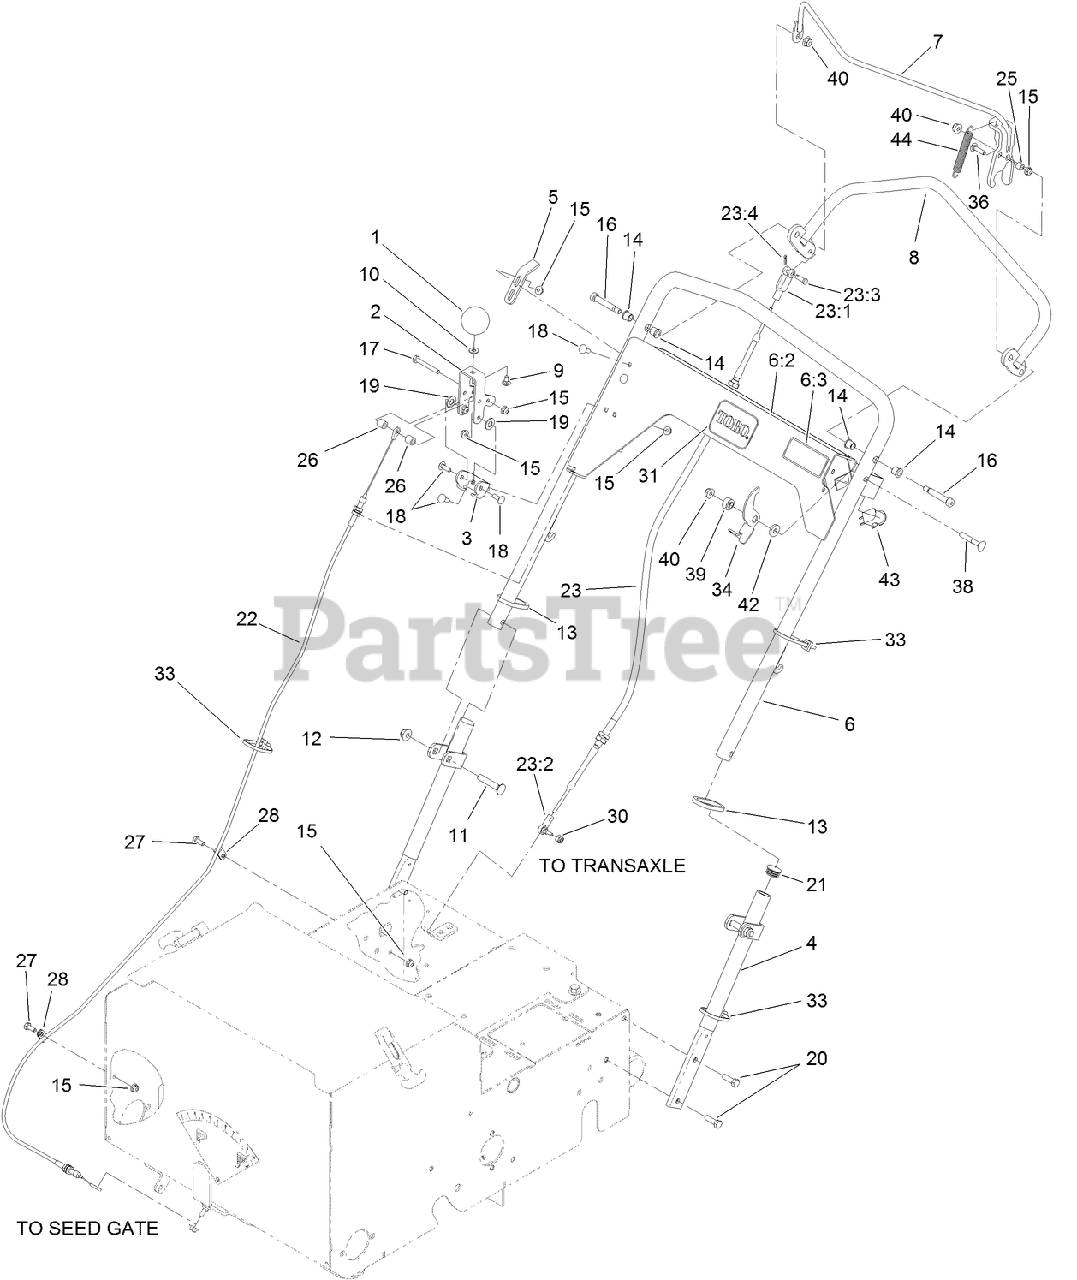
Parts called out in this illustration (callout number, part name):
1	KNOB-RATE, FLOW
2	LEVER-ADJUST, FLOW
3	BRACKET-ADJUST, FLOW
4	HANDLE-LOWER
5	BRACKET-ADJUST, DRIVE
6	HANDLE
6:2	DECAL-CONTROL PANEL, SEEDER
6:3	DECAL-SAFETY LATCH
7	BAIL-CLUTCH
8	HANDLE-DRIVE
9	SCREW-CARR
10	WASHER-FLAT
11	SCREW-CARR
12	NUT-HF, NI
13	RING-HANDLE LOCK
14	BEARING
15	NUT-HF
16	SCREW-SHOULDER
17	SCREW-HH
18	BOLT-CARR
19	WASHER-PLAIN
20	SCREW-HH
22	CABLE-FLOW, SEED
23	CABLE-PUSH PULL
23:1	CLEVIS
23:2	BALL JOINT
23:3	PIN-CLEVIS
23:4	PIN-COTTER
25	SPACER
26	SPACER
27	SCREW-HH
28	CLAMP-R
30	NUT-LOCK
31	DECAL
33	TIE-CABLE
34	LATCH-BAIL
36	SCREW-CARR
38	SCREW-HANDLE
39	BUSHING-STEPPED
40	NUT-HF, NI
42	WASHER-FLAT
43	SWITCH-BAIL
44	SPRING
